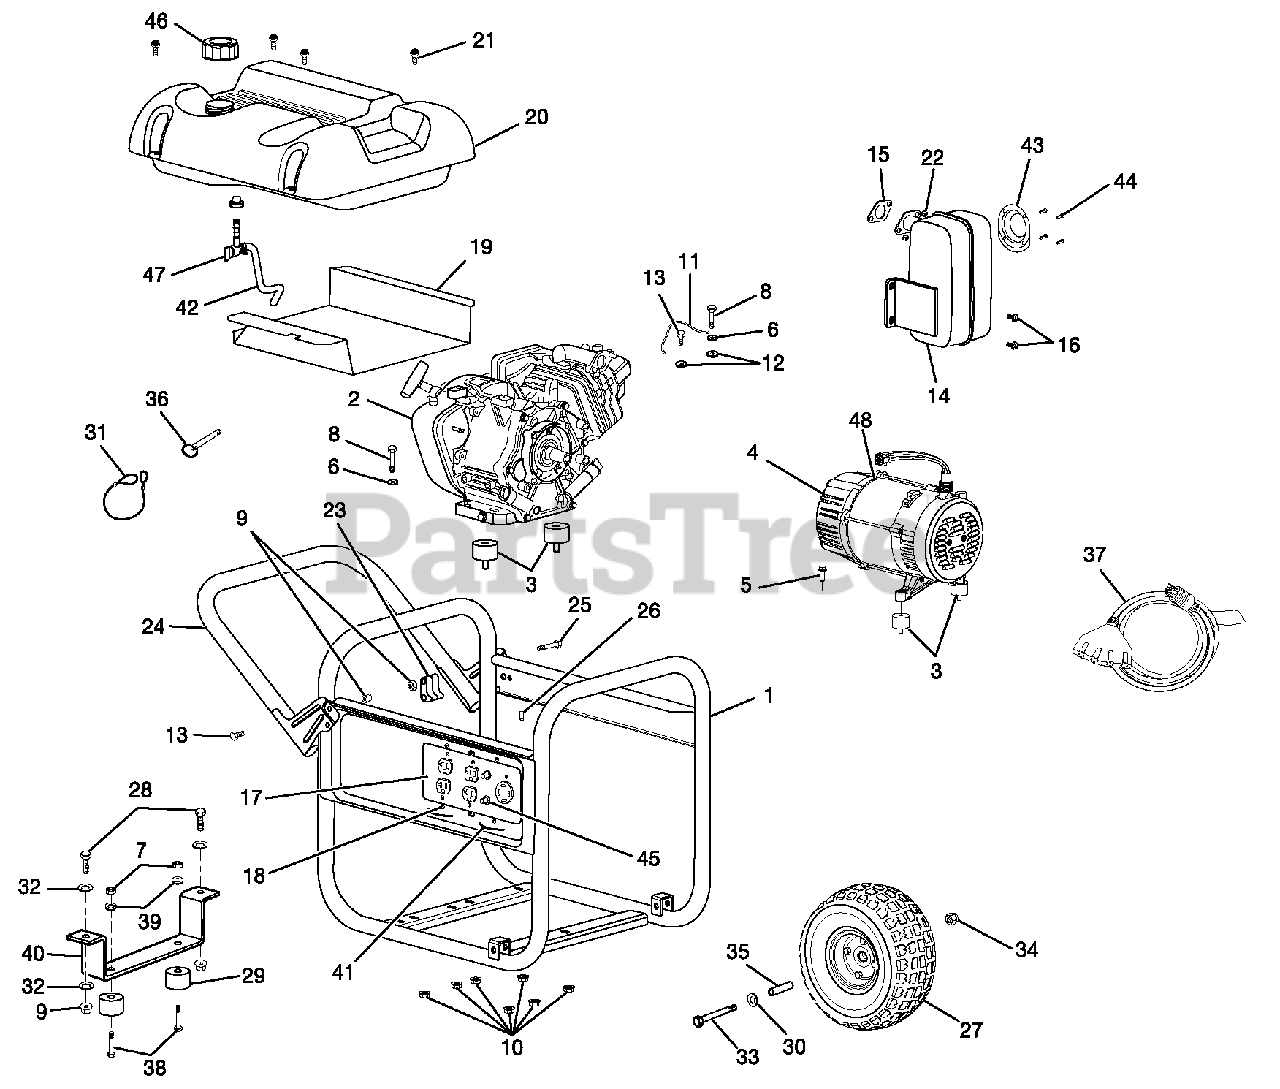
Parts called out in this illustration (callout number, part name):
1	Frame Assembly
2	Engine (Subaru OHC)
4	Generator Head Assembly
5	Bolt (5/16-24 x 6-5/8 in., Hex Hd.)
6	Lock Washer (5/16 in.)
7	Lock Nut (1/4-20)
8	Bolt (5/16-18 x 1-1/2 in.)
9	Lock Nut (5/16-18)
10	Flange Nut (5/16-18)
11	Ground Wire Assembly
12	Washer (5/16 in.) External Star
13	Bolt (5/16-18 x 3/4 in., Hex. Hd.)
16	Bolt (5/16-24 x 5/8 in.)
17	Wire Panel
18	Screw (6-19 x 1/2 in.)
19	Heat Shield
20	Fuel Tank Assembly
21	Screw (#10 x 1 in.)
22	Nut (8 mm)
23	Handle Lock Bracket
25	Bolt (5/16-18 x 1-3/4 in.)
26	Rubber Cap
27	Wheel (10 in.)
28	Bolt (5/16-18 x 1 in.)
29	Rubber Foot
30	Washer (3/8 in.)
32	Washer (5/16 in.)
33	Bolt (3/8-16 x 4-1/4 in.)
34	Lock Nut (3/8-16)
35	Spacer (.38 ID)
36	Handle Lock Pin
37	Extension Cord (25 foot, 20 amp)
38	Bolt (1/4-20 x 1-1/2 in.)
39	Washer (1/4 in.)
40	Frame Support
41	Cord Retainer
42	Fuel Line Assembly
43	Spark Arrester Screen
44	Screw (8-32 x 3/8 in.)
45	Circuit Breaker (25 amp)
47	Fuel Shut Off with Filter
48	Generator Head Cover
